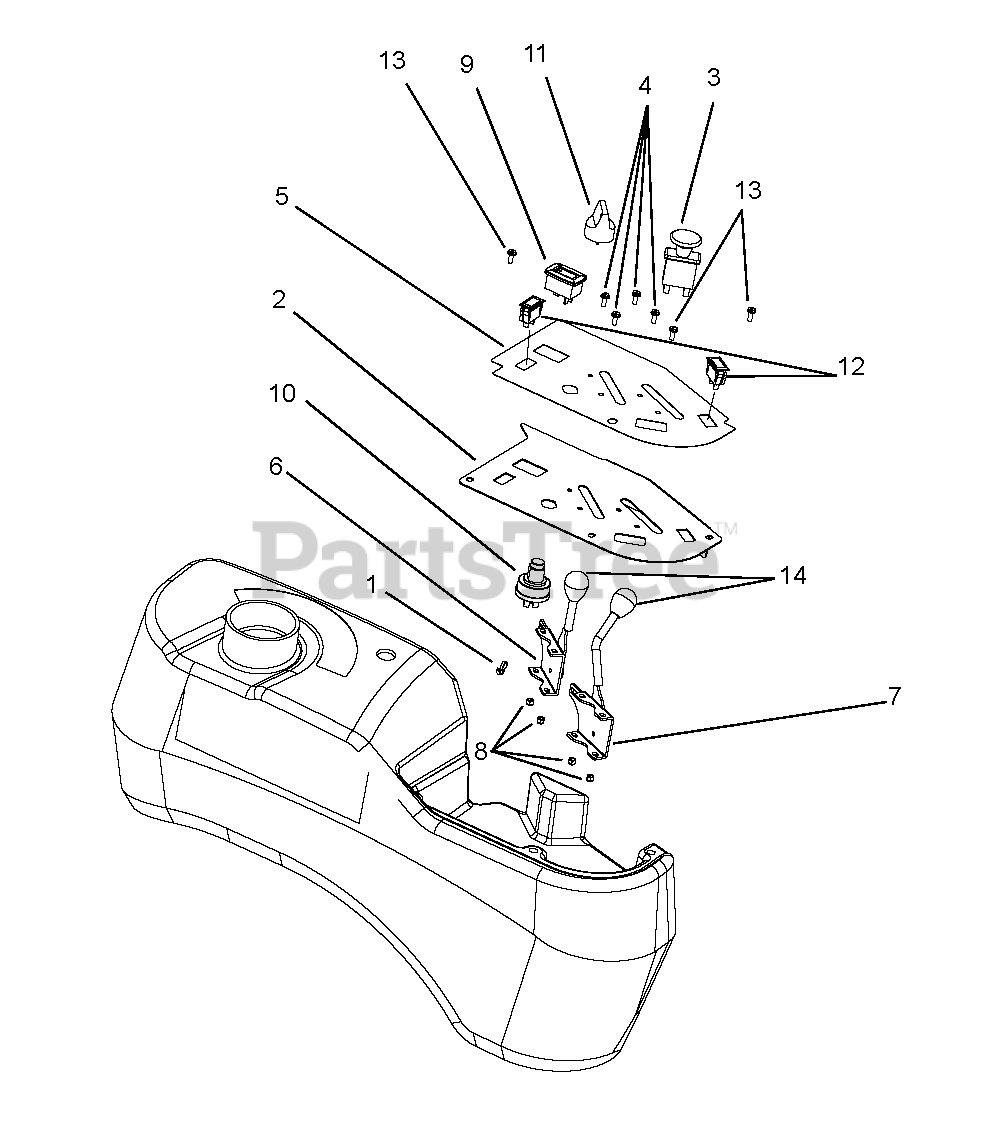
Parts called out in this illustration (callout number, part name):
1	Cable Tie w/ Tree (.25 HOLE)
2	Panel, Control
3	Switch, Clutch
4	Screw, Machine 10-24X.50 Hex Washer Head
5	Decal, Control Panel
6	Cable, Pro-Control Choke
7	Cable, Pro-Control Throttle
8	Nut, Locking Nylon 10-24 W/INSRT YWZC
9	Meter, Hour with Maintenance
10	Switch, Ignition
11	Key, with Shield
12	Light, Indicator
13	Screw, Machine 10-24 x .50 Hex Washer Head Stainless
14	Knob, Control, Black .38-16 x .50
